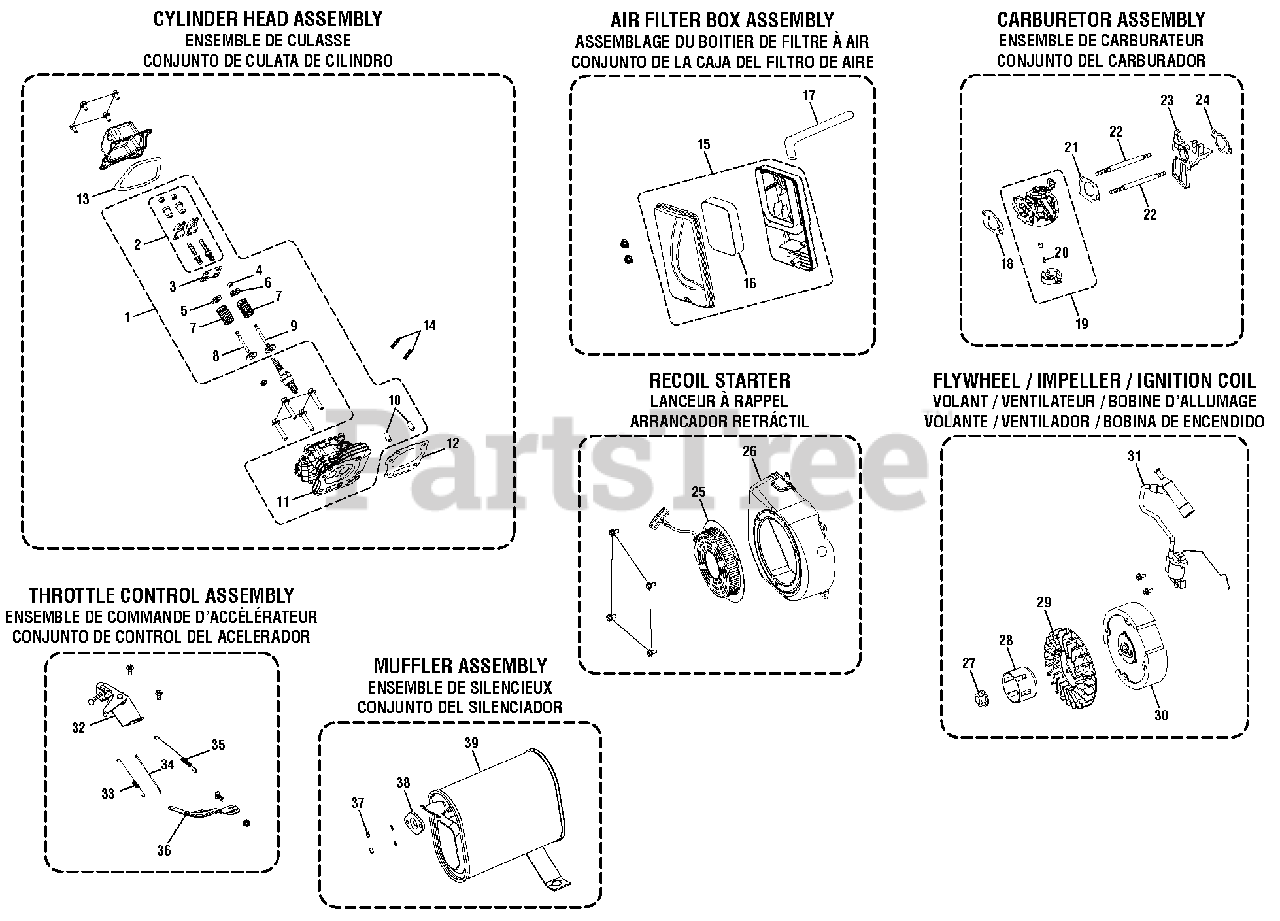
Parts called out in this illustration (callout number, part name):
1	Cylinder Head Assembly
2	Rocker Assembly
3	Guide Plate
4	Rotator
5	Valve Spring Seat (Intake)
6	Valve Spring Seat (Exhaust)
7	Valve Spring
8	Intake Valve
9	Valve Exhaust
10	Dowel Pin
11	Cylinder Head
12	Cylinder Head Gasket
13	Cylinder Head Cover Gasket
14	Threaded Stud
15	Air Cleaner Assembly
16	Air Filter
18	Spacer
19	Carburetor Assembly
20	Needle Valve
21	Carburetor Gasket
22	Threaded Stud
23	Carburetor Insulator
24	Intake Gasket
25	Recoil Starter
26	Recoil Starter Cover
27	Nut
28	Starter Pulley
29	Recoil Starter Fan
30	Flywheel Assembly
31	Ignition Coil Assembly
32	Throttle Assembly
33	Governor Spring
34	Governor Rod
35	Throttle Return Spring
36	Governor Arm
37	Hex Nut
38	Exhaust Gasket
39	Muffler Assembly
